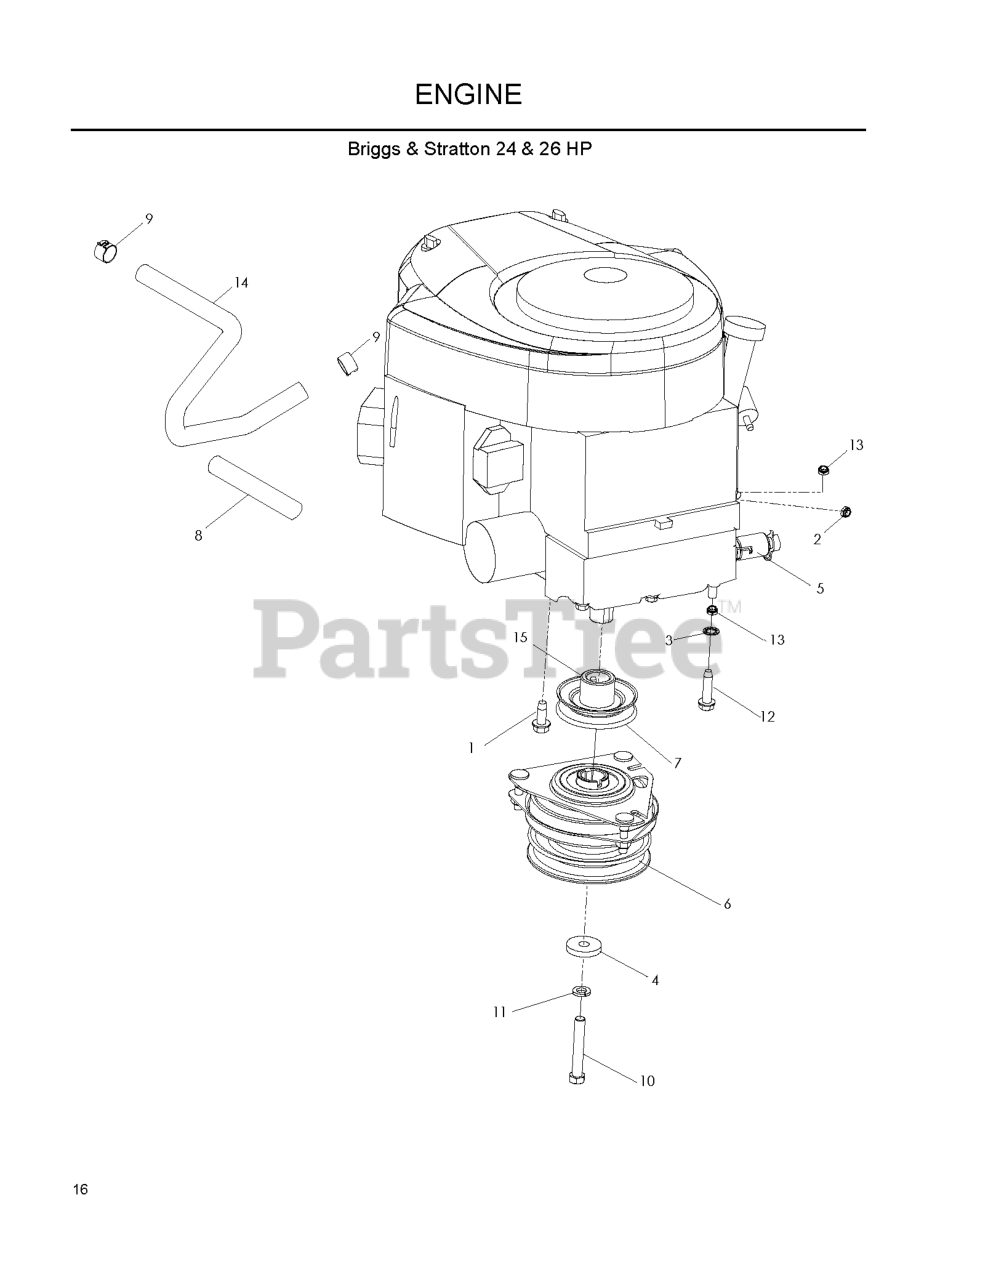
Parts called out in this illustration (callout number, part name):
1	BOLT 3/8-16 X 1.0
2	JAM NUT 1/4C (2 2 PW01)
3	WASHER, 3/8 ITLW ZN
4	CLUTCH, WASHER
5	OIL DRAIN FITTING
6	RB.CLUTCH.OGURA.4.4.PD
7	PULLEY, ENGINE
8	FUEL LINE 5"
9	HOSE CLAMP
10	HEX SCREW 7/16-20 X 3
11	WASHER 7/16 LOCK
12	BOLT 3/8-16 X 1 1/2 ZINC CLEAR
13	NUT 3/8-16 NYLOC
14	FUEL LINE 13"
15	SPACER, ENGINE - PULLEY
